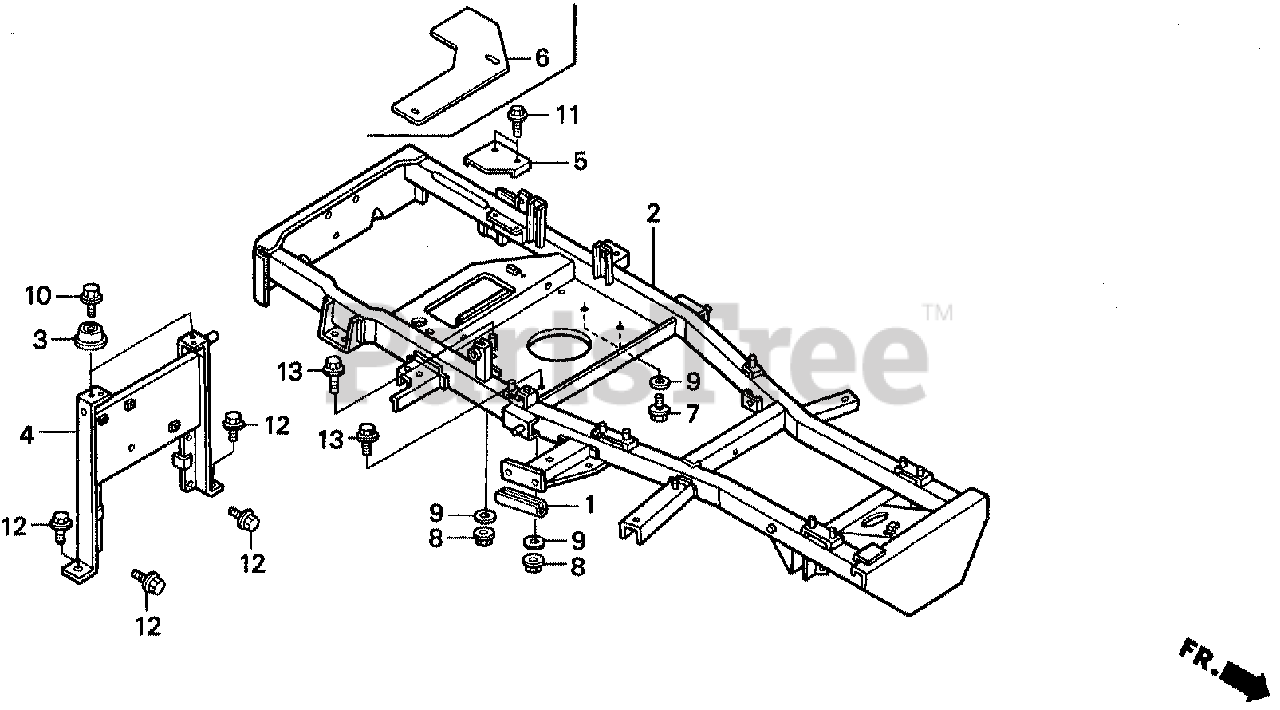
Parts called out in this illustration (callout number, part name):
1	TRIM, FUEL TANK (SOURCE: VINTAGE PARTS INC.)
3	RUBBER (LOWER)
4	FRAME, SEAT SUPPORT
7	BOLT, FLANGE (5/16"X22)
8	NUT, FLANGE (8MM)
9	WASHER, PLAIN (8MM)
10	BOLT, FLANGE (6X12)
12	BOLT, FLANGE (8X16)
13	BOLT, FLANGE (8X35)
